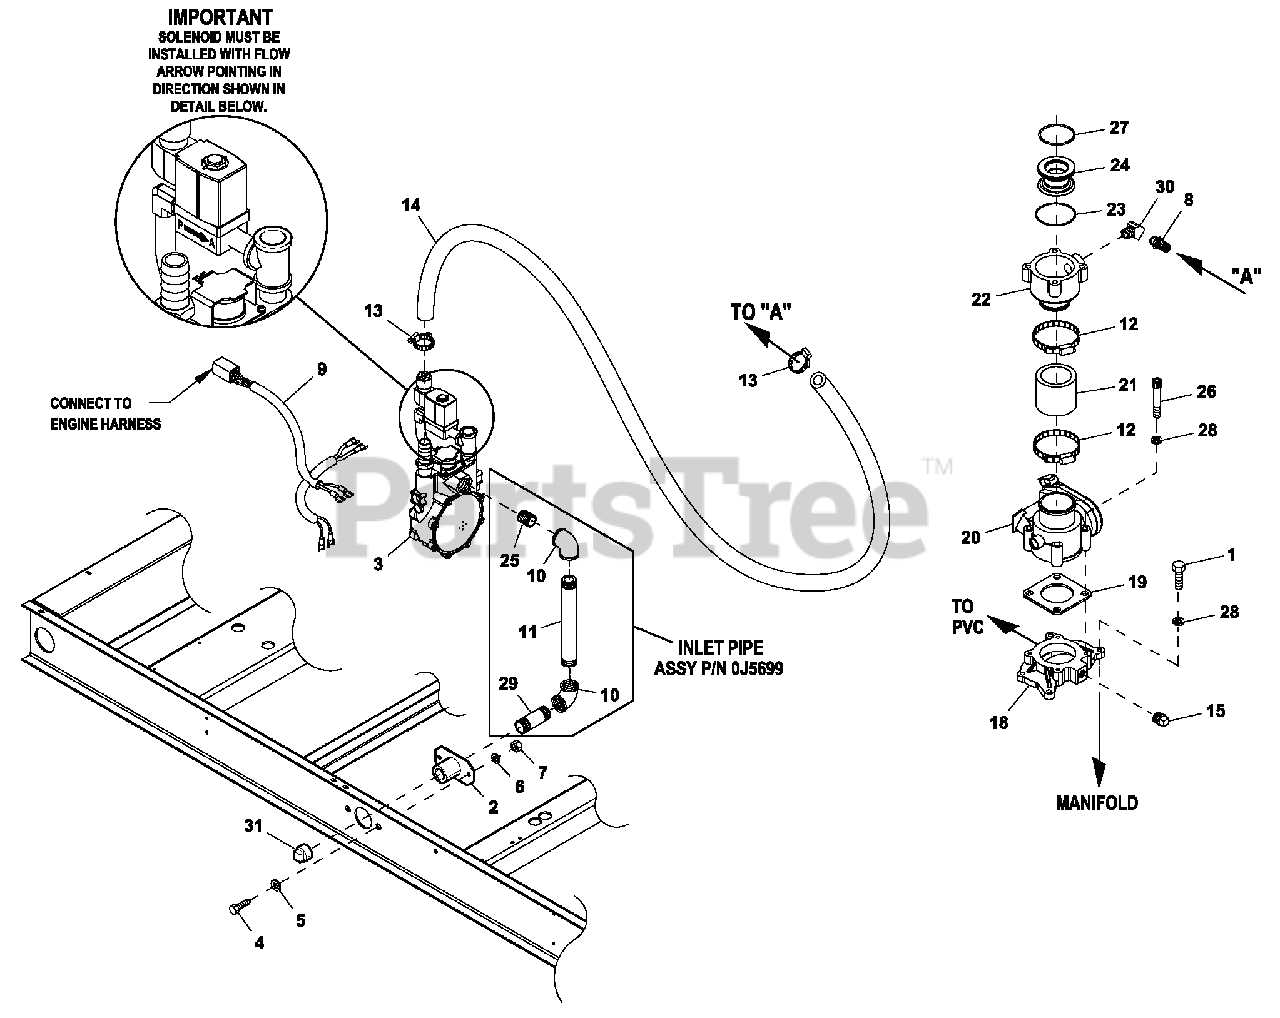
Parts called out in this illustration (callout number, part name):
1	SCREW HHC M6-1.0 X 25 G8.8
2	FLANGE FUEL INLET
3	REGULATOR ASSY 5.4L 48 KW 49ST
4	SCREW HHC M8-1.25 X 20 G8.8
5	WASHER FLAT 5/16-M8 ZINC
6	WASHER LOC KM8-5/16
7	NUT HEX M8-1.25 G8 CLEAR ZINC
8	BARBED STR 1/2NPTX3/4
9	HARN FUEL JUMPER SINGLE REG
10	ELBOW 90D 3/4 NPT
11	NIPPLE PIPE 3/4NPTX 5-1/2 LG
12	CLAMP HOSE #36 1.88-2.75
13	CLAMP HOSE #10 .56-1.06
14	HOSE 3/4 ID SAE-30R2 (40" LG)
15	PLUG STD PIPE 1/4 STEEL SQ HD
18	MACHINING INTA KE ADAPTOR 40MM
19	GAS KET BOSCH 32 & 40
20	ACTUATOR BOSCH 40 GOVERNOR
21	HOSE COOLING 2IN ID 20R4 (2IN)
22	MIXER ACTUATOR 40MM MACHINED
23	O-RING 47.625 ID X 2.38 WIDTH
24	VENTURI THROTTLE 26MM
25	NIPPLE CLOSE 3 /4X 1 .3 75
26	SCREW SHC M6-1.0 X 50 C8.8
27	O-RING 45.63 ID X 2.62 WIDTH
28	WASHER LOC KM6-1/4
29	NIPPLE PIPE 3/4NPT X 2
30	ELBOW 45D STREET 1/2NPT BRASS
31	PLUG STD PIPE 3/4 STEEL SQ HD
